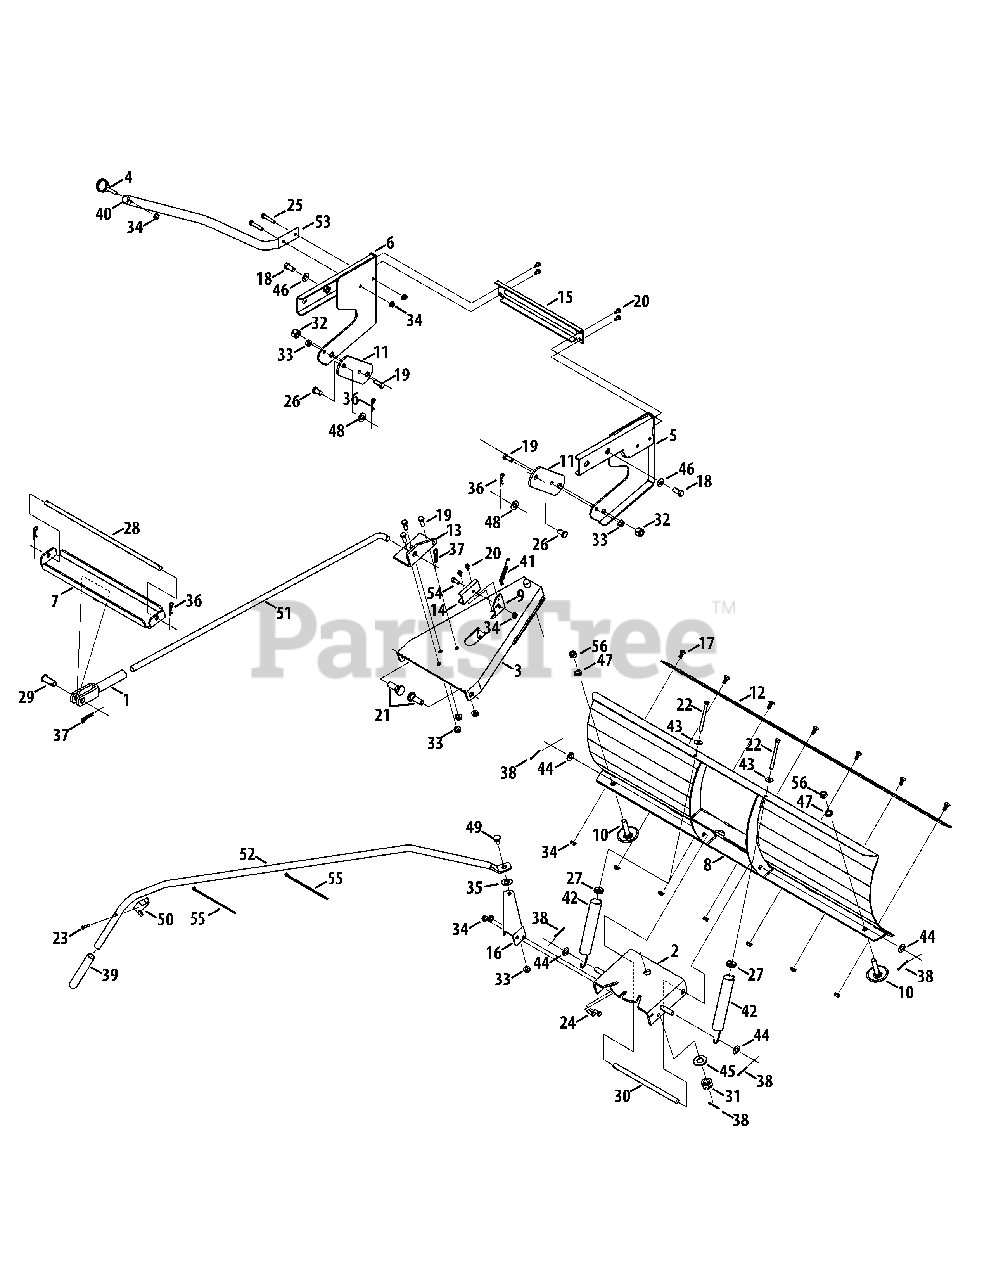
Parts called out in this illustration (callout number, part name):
1	Adjustment Clevis Assembly
3	Blade Frame Assembly
4	Eyebolt Assembly
5	RH Hitch Bracket Assembly
6	LH Hitch Bracket Assembly
7	Lift Bracket Assembly
8	Blade Assembly, 46"
9	Blade Lock Plate Assembly
10	Skid Shoe Assembly
11	Blade Link Bracket
12	Shave Plate, 46"
16	Blade Adjustment Arm
17	Carriage Bolt, 5/16-18 x .750
18	Hex Screw, 7/16-14 x 1.00
19	Hex Screw, 3/8-16 x 1.00
20	Hex Washer Screw, 1/4-20 x 0.500
21	Shoulder Screw, 1/2-13 x .625 x .36
22	Hex Screw, 5/16-18 x 3.50
23	Machine Screw, #10-24 x 1.375
24	Hex Screw, 5/16-18 x .75
25	Hex Screw, 5/16-18 x 1.75
26	Clevis Pin, .50 x .78
27	Spring Insert
28	Rod, .50 x 18.61
29	Clevis Pin
30	Rod, .50 x 10.428
31	Slotted Nut, 3/4-16
32	Nut, 1/2-13, Hex Lock Nylon
33	Flange Lock Nut, 3/8-16
34	Flange Lock Nut, 5/16-18
35	Flat Teflon Washer, .570 x 1.12 x .062
36	Click Pin, .092 x 1.64
37	Cotter Pin, .125 x 1.75
38	Cotter Pin, 1/8 x 1.25
39	Foam Grip
40	Button Plug, 750
41	Extension Spring, .38 x 3.25
42	Extension Spring, 1.25 x 6.7
43	Flat Washer, .349 x .879 x .063
44	Flat Washer, .530 x .930 x .050
45	Flat Washer, .760 x 1.50 x .120
46	Bell Washer, .45 x 1.00 x .062
47	Lock Washer, 1/2
48	Flat Washer, .531 x 1.062 x .134
49	Shoulder Bolt, .496 x .336 x 3/8-16
50	Blade Release Cable & Lever
52	Blade Adjustment Handle
54	Shoulder Screw, 5/16-18 x .405 x .435
55	Cable Tie
56	Nut, 1/2-13, Jam
